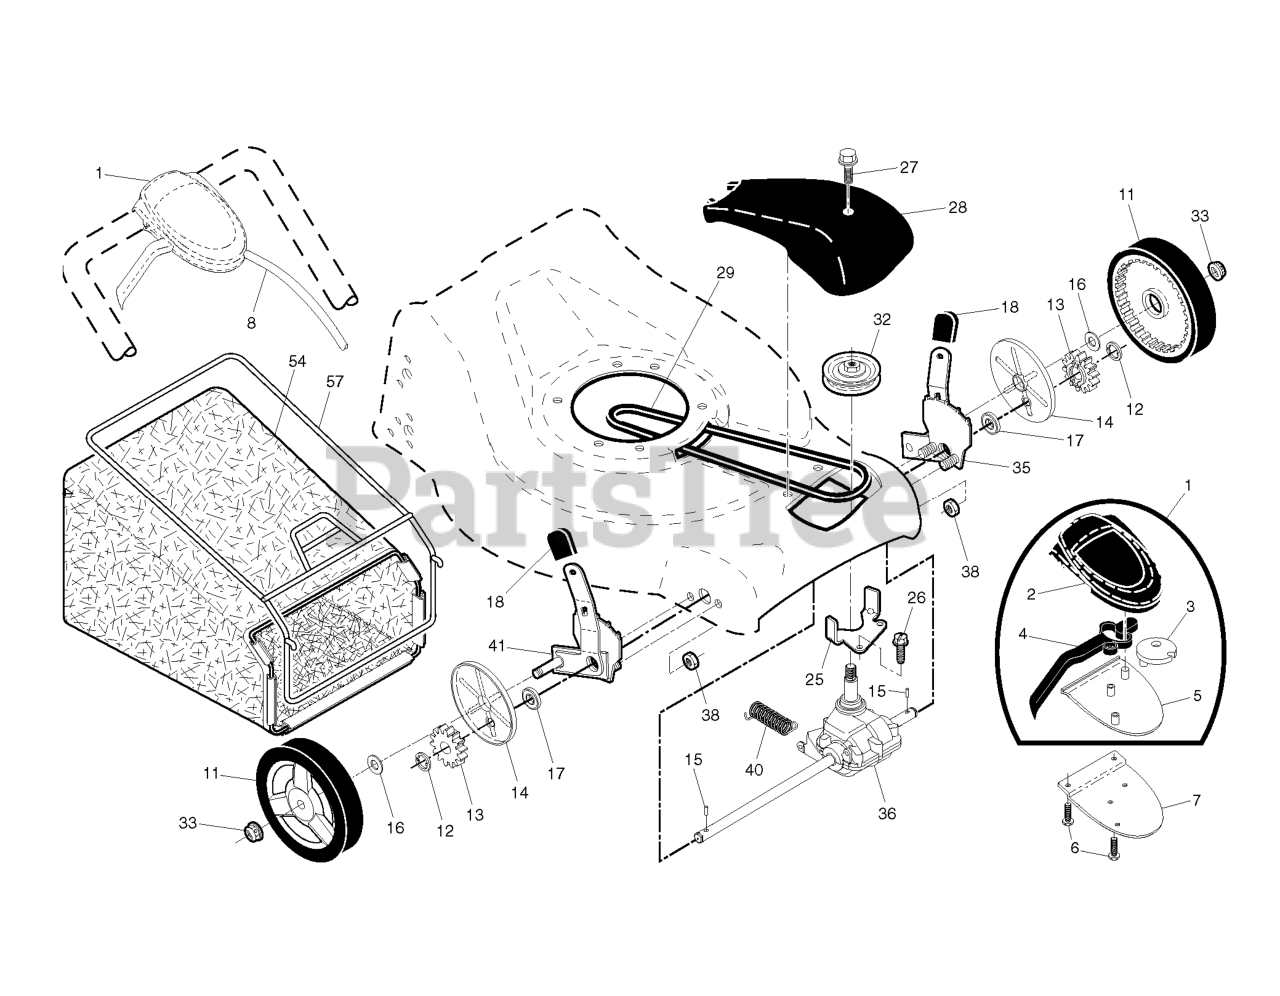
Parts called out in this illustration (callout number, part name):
1	CONTROL.DR.QW.21FGD.BS.GY/BLK
2	COVER TOP AUTO WALK CONTROL
3	PULLEY.CAM.DRIVE.CONTROL.EZ
4	LEVER.BLACK
5	COVER BOTTOM AUTO WLK CONTROL
6	SCREW, PHILLIPS HEAD 10 X 5/8
7	BRACKET.DRIVE.CONTROL.MOUNT.BL
8	CABLE ASSEMBLY, DRIVE
11	WHEEL.8X1.75.H3SPK.RAD3.GY.BU3
12	E-RING 7/16 RE
13	PINION.14.TEETH.FGD
14	COVER.DUST.WHEEL
15	PAWL, DRIVE
16	WASHER FLUT
17	BEARING.ASM.
18	SELECTOR KNOB
25	BELT KEEPER
27	SCREW, HEX HD TAPPING #10-24 1
28	COVER.DRIVE.21.FWGD.GRAY
29	BELT.DRIVE.FG
32	RP PULLEY.DRIVE.EZ
33	NUT.HEX.FLANGE.3/8-16.LO(3 2)
35	RP KIT, WHEEL ADJUSTER, LH
36	TRANSMISSION.21.FGD.HT.VST
38	LOCKNUT.NYLOC.1/4-20
41	KIT, WHEEL ADJUSTER, RH
54	RB GBAG.33230247T.SIL.HUSQ.BLU
57	FRAME.GBAG.21.FWGD
